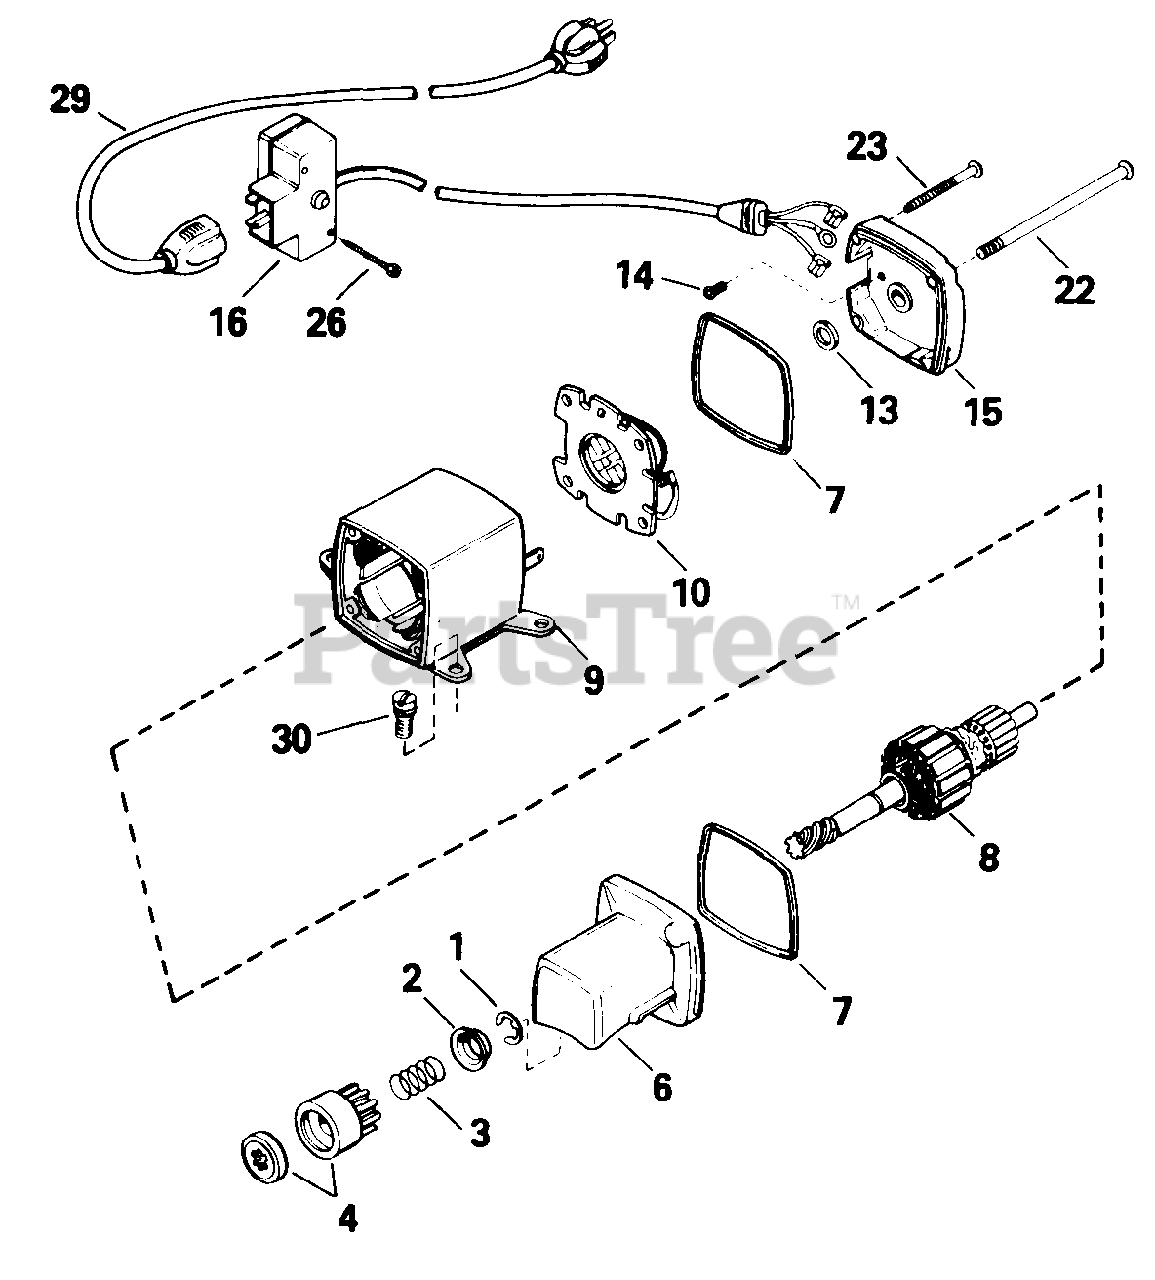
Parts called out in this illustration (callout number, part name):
1	Ring, Retainer
2	Retainer, Spring
3	Spring, Anti-Drift
4	Nut & Gear
6	Cap Ass'y., Drive End
8	Armature
9	Housing Ass'y.
10	Card Ass'y., Brush
13	Washer, Thrust
14	Screw, Ground
15	Cap Ass'y., Commutator End
16	Box Ass'y., Switch
22	Bolt, Case
23	Screw, Grounding
26	Screw, Hex Hd. Self-Tap, 6-32 x 2 1/2
29	Cord, Extension (10'6")
30	Screw, Hex Hd. Self-Tap, 1/4-20 x 11/16
